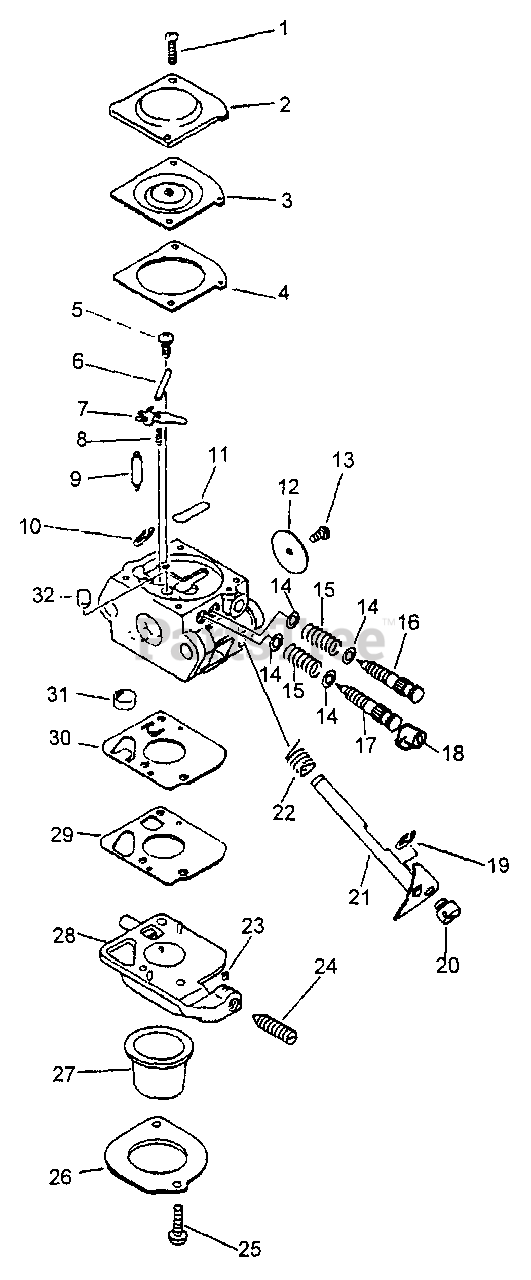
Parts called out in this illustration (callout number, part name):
2	COVER, METERING DIAPHRAGM
3	DIAPHRAGM, METERING
4	GASKET, METERING
5	SCREW, METERING LEVER PIN
6	PIN, METERING LEVER
7	LEVER, METERING
8	SPRING, METERING LEVER
9	VALVE, NEEDLE
11	PLUG, WELCH
12	VALVE, THROTTLE
15	SPRING, NEEDLE
16	NEEDLE, IDLE
17	NEEDLE, HIGH SPEED
18	CAP, LIMITER - RED
21	SHAFT, THROTTLE
22	SPRING, THROTTLE RETURN
23	PIECE, FRICTION
24	SCREW, IDLE ADJUST
26	RETAINER
27	BULB, PURGE
28	BODY ASSY, PURGE
31	STRAINER
32	NOZZLE, CHECK VALVE
